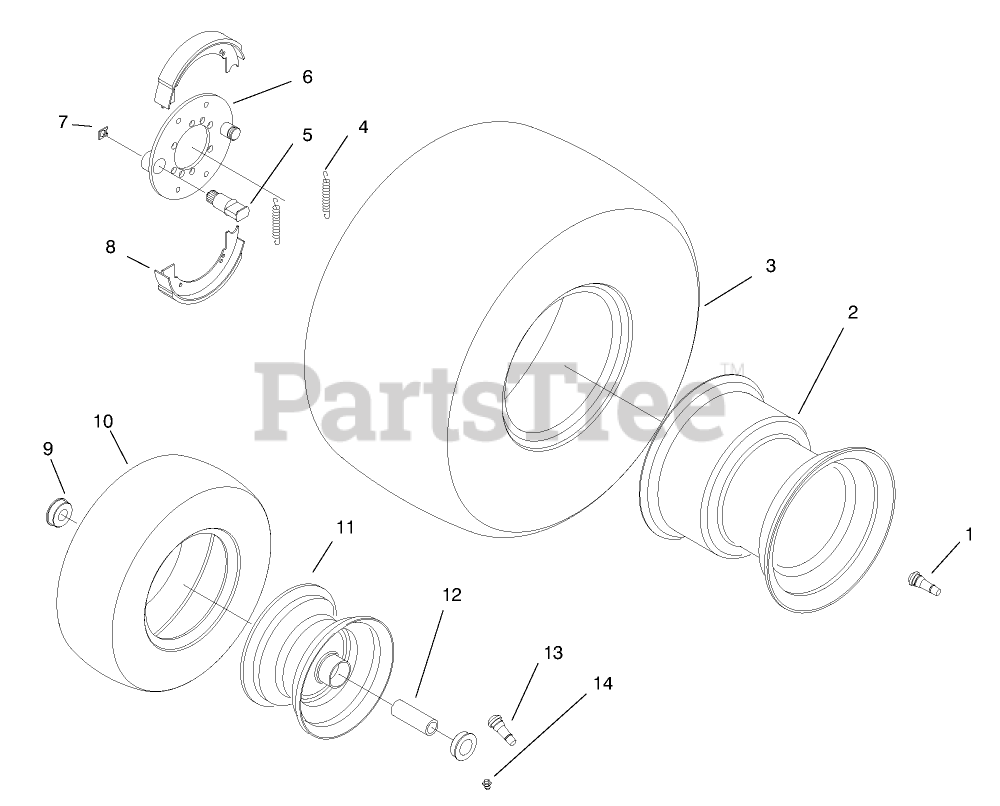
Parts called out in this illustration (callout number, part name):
1	VALVE
2	WHEEL-REAR
3	TIRE 22 X 11.00-8
4	SPRING-RETURN
5	Cam Shaft
6	PLATE-BACKING
7	Clip
8	SHOE-BRAKE
9	BEARING BALL
10	TIRE-FRT 13X5.00-6
11	WHEEL - FRONT
12	SPACER FRT WHEEL INN
13	VALVE
14	FITTING-GREASE
